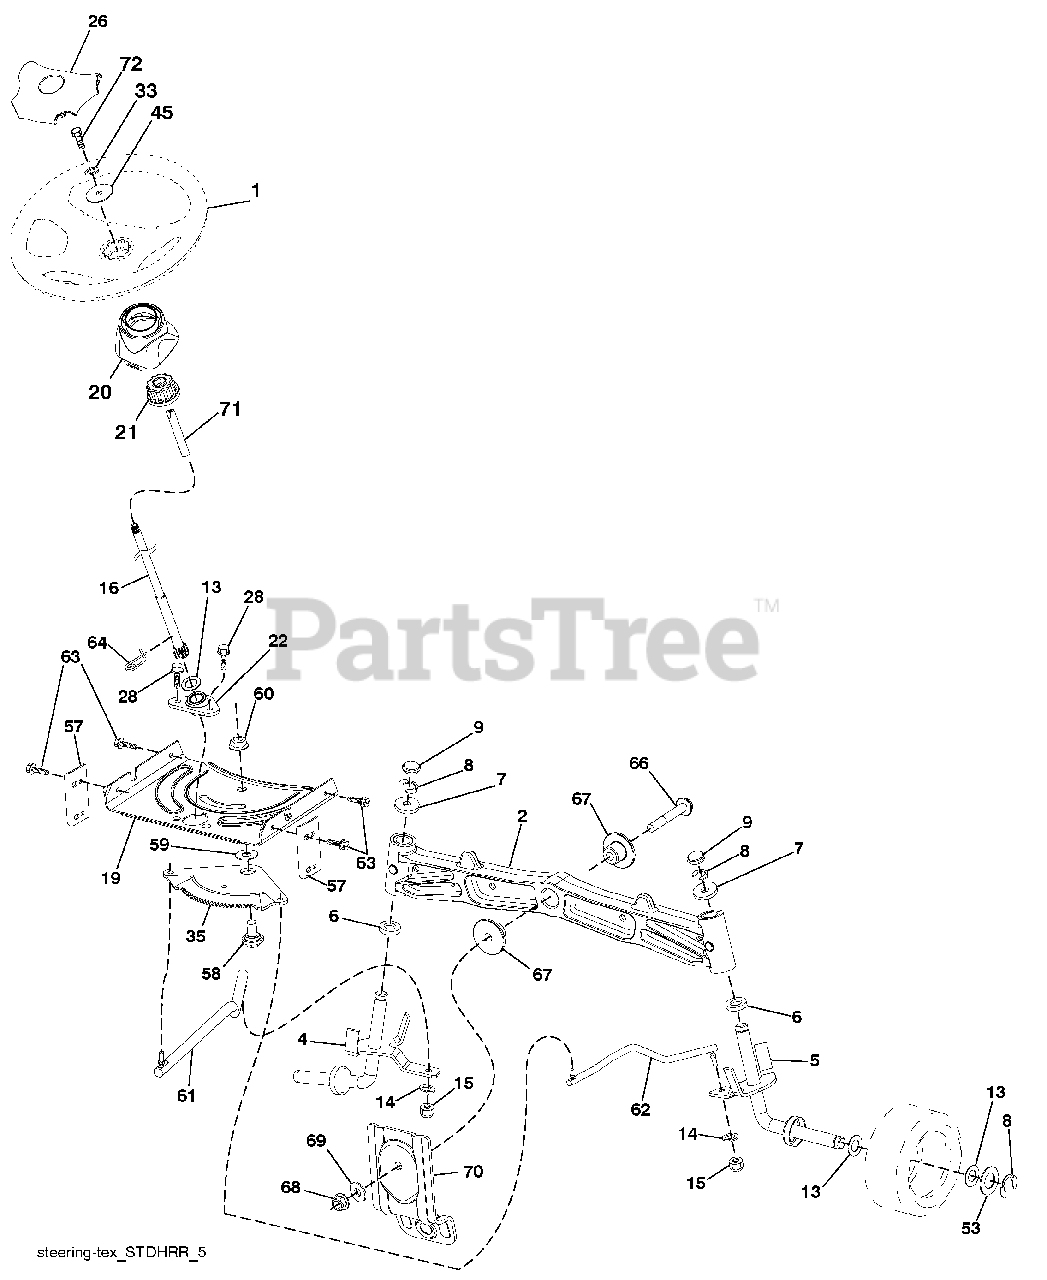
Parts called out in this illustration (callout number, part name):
1	Wheel, Steering
2	Axle Asm., Front
4	Spindle Asm., LH
5	Spindle Asm., RH
6	Washer Thrust 0.75 x 1.23
7	Washer 25/32 x 1-5/8 x 16 Ga.
8	Ring, Clip #T5304-75
9	Cap, Spindle
13	Washer 25/32 x 1-1/4 x 16 Ga.
14	Washer Lock 3/8
15	Nut, Crown Lock 3/8-24 unf
16	Shaft Steering
19	Plate Steering
20	Boot, Steering
21	Adapter, Wheel Steering
22	Strg. Supt. Lower
26	Insert, Wheel Steering
28	Screw 3/8-16 x 3/4
33	Washer Lock 5/16
35	Gear, Sector Plate
45	Washer 11/32 x 2-3/8 x 12 Ga.
53	Washer Hardened .793 x 1.637 x .060
57	Bracket Upstop
58	Bolt Shoulder Sector Pivot CFM
59	Washer Thrust Sector Steering
60	Nut Flange Lock 5/8-11
61	Draglink, LH
62	Draglink, RH
63	Screw 5/16-18 x 3/4
64	Retainer Clip Spring Steering
66	Bolt Hex Fghd 7/16-14 x 3 Serr
67	Bushing PM Front Axle
68	Nut Lock Flange 7/16-14 Gr. 5
69	Washer 1.5 x .505 x .118
70	Bracket Deck Susp. Front
71	Shaft Ext. Steering
72	Bolt 5/16-18 x 5 Gr. 5
